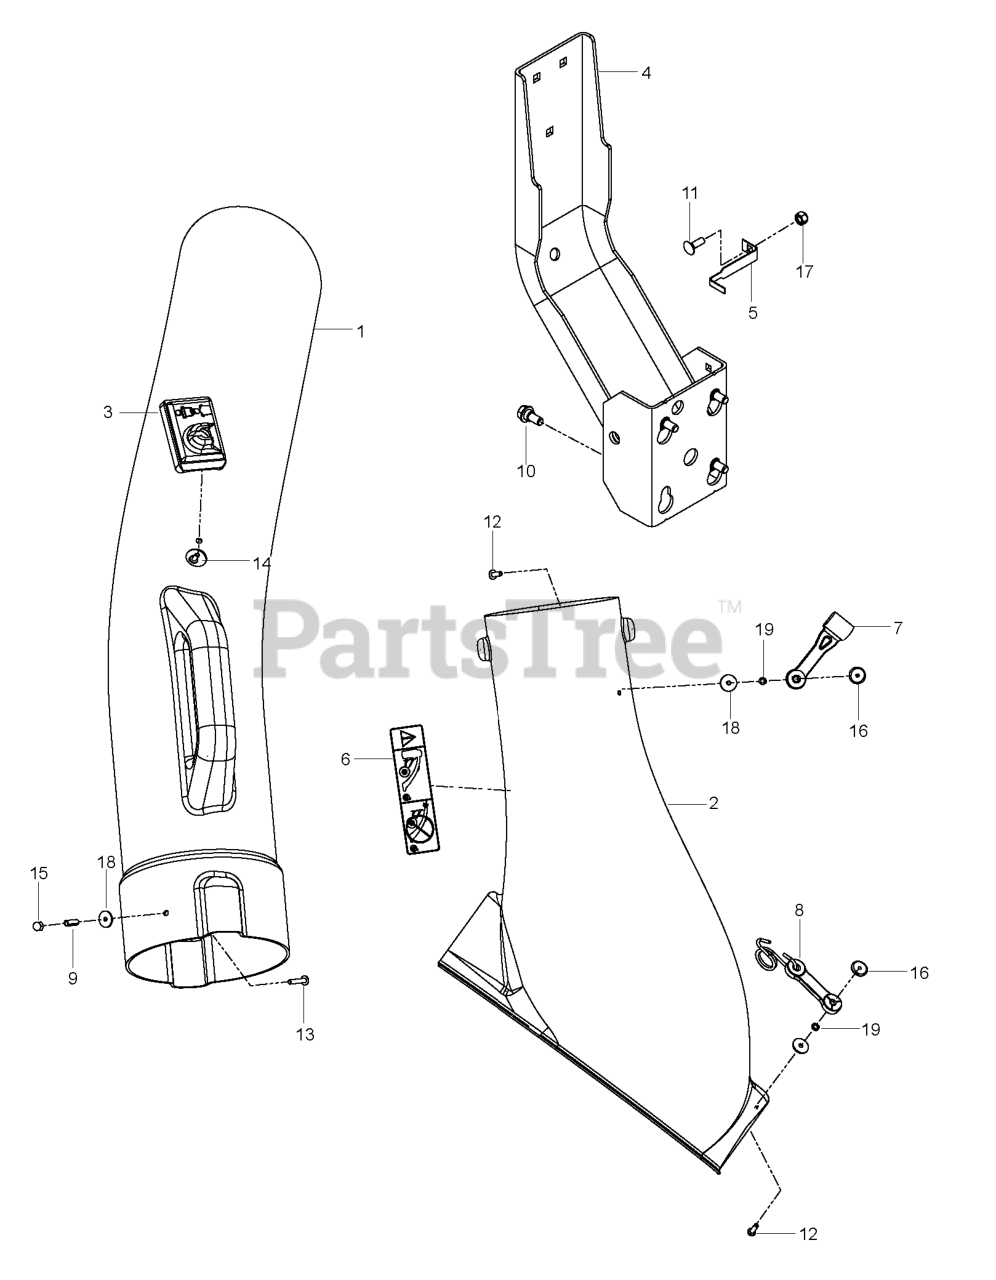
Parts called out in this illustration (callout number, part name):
1	CHUTE.UPPER.42FCS.TRACTOR.BLK
2	CHUTE.LOWER.FCS.TRACTOR.BLACK
3	INDICATOR ASM BAG
4	POST.SUPPORT.BAGGER.BLACK
5	STOP BRACKET, BAGGER 2 BIN
6	DECAL, CHUTE
7	LATCH ASSY
8	LATCH.HOOD.
10	SHOULDER BOLT 5/16-18TT
12	SCREW
13	SCREW
15	NUT
16	WELDNUT
17	LOCKNUT.NYLOC.1/4-20
18	RP STEEL WASHER
19	LOCKWASHER #10
